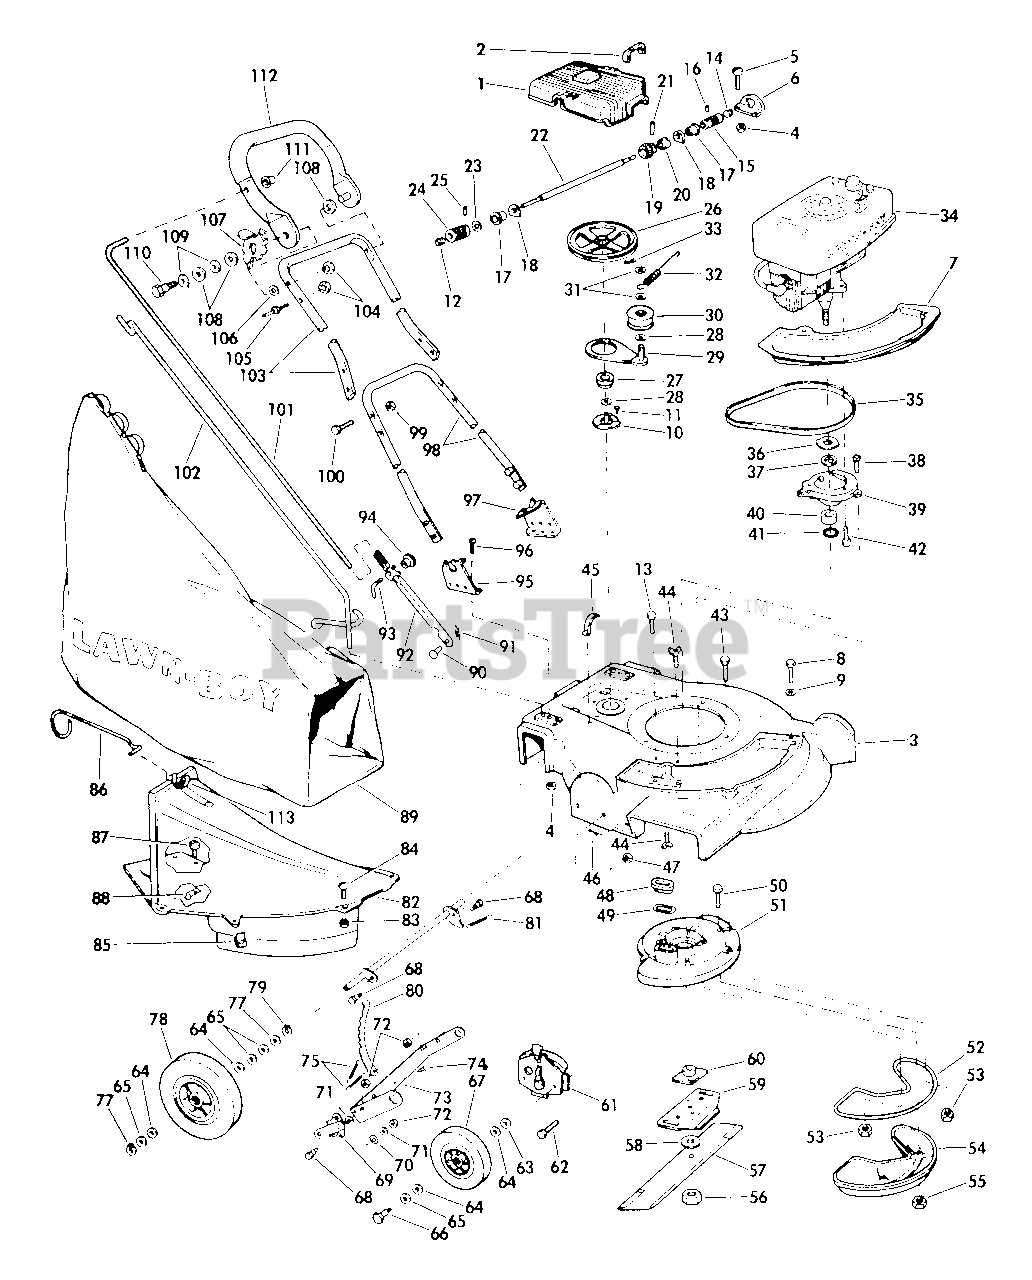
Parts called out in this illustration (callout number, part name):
1	Cover-Pulley
2	Seal-Dust, Cover
3	Housing, Drive Shaft Bracket Assy.
4	Nut-Nylok
5	Screw-Machine, Drive Shaft Brkt.
6	Bracket-Drive Shaft
7	Cover-Chute Opening
8	Hex Head
9	Grommet-Plastic
10	Cup, Pin & Rivet Assy.
11	Rivet
12	Speed Nut
13	Screw
14	Plug-Grease, Roller
15	Roller-Drive Shaft, Left
16	Screw-Set
17	Sleeve & Brg. Assy. Drive Shaft
18	Seal-Drive Shaft Cover
19	Gear-Drive Shaft & Sleeve Assy.
20	Sleeve-Drive Shaft Gear
21	Pin-Spiral
22	Drive Shaft
23	Washer-Drive Shaft
24	Roller-Drive Shaft, Right
25	Screw-Set
26	Pulley Assembly, Complete
27	Felt-Oiler (Cup)
28	Shim, .025
28	Shim, .010
28	Shim, .020
29	Idler Arm & Pin Assy.
30	Idler Pulley & Brg. Assy.
31	Washer-Idler
32	Spring-Idler, Tension
33	Pin-Cotter
34	Engine, Model D-420
35	Belt-"V", 31", Class 3L, Fractional H.P.
36	Washer-Felt, Seal Retainer
37	Seal-Sub-base, Felt
38	Screw-Sub-base Mounting
39	Sub-base & Bearing Assy.
40	Bearing-Needle
41	Seal-Sub-base
42	Bolt-C'case to Sub-base
43	Screw-Muffler Pl. to Housing
44	Wing Screw
45	Clip-Spring, Cover
46	Pin-Cotter, Spring Clip
47	Nut-Nylok
48	Sleeve-Muffler Gasket
49	Gasket-Exhaust
50	Scr.-Muffler to Muffler Plate
51	Plate Muffler
52	Gasket Muffler
53	Nut-C'case to Muffler Plate
54	Muffler
55	Nut-Muffler Mounting
56	Nut-Blase
57	Blade, 21"
58	Washer-Blade
59	Blade Stiffener
60	Collar & Plate Assy.
61	Height Adjustment Assy.
62	Screw-Height Adjustment
63	Washer-Wheel, Front
64	Washer, Felt
65	Washer (See Note #1)
66	Bolt-Shoulder, Wheel
67	Wheel & Tire Assy. 6"
68	Bolt-Shoulder
69	Clutch Assembly
70	Washer-Lock Comp. Lever
71	Washer
72	Nut-Nylok
73	Bracket-Axle
74	Pin-Height Adj. Lever
75	Spring-Height Adjustment
76	Axle & Torque Lug Assy.
77	Ring-Retaining, Axle
78	Wheel & Tire Assy. 8"
79	Washer-Axle
80	Lever-Height Adjustment
81	Spring-Torque Lug
82	Skirt Assembly
83	Nut
84	Screw
85	Speed Nut
86	Wheel Guard Assy.
87	Screw
88	Speed Nut
89	Grass Bag
90	Pin-Control Lever
91	Hair Pin
92	Control Lever Assembly
93	Screw-Control Lever
94	Nut-Control Lever
95	Handle Bracket, Right
96	Screw-Handle Bracket
97	Handle Bracket, Left
98	Handle and Pin Assy.
99	Nut-Handle
100	Screw-Handle
101	Control Rod
102	Rod Assembly
103	Handle Section-Center
104	Nut-Nylok
105	Lockout Pin Assy.
106	Washer
107	Clip-Lockout
108	Washer
109	Wave Washer
110	Bolt
111	Palnut
112	Handle and Grip-Top
113	Clip-Plastic Chute
113	Clip-Metal Chute
